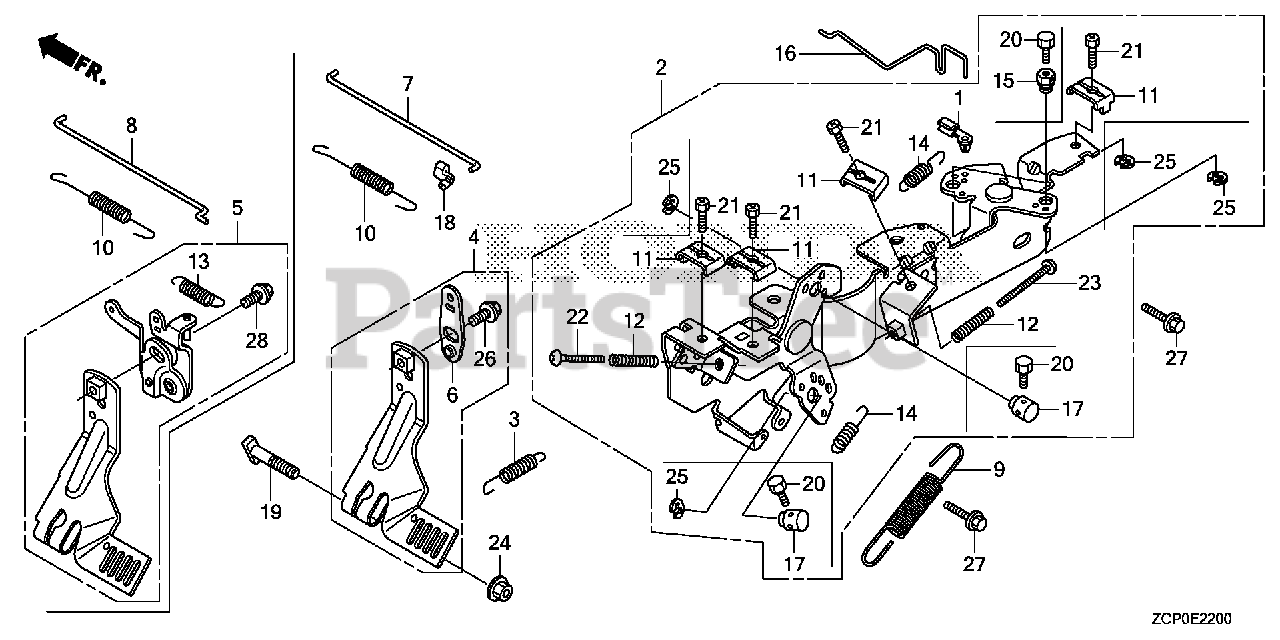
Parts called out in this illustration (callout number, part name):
1	JOINT, ROD
2	CONTROL ASSY.
3	SPRING, STARTER
5	ARM, GOVERNOR
8	ROD, GOVERNOR
9	SPRING, GOVERNOR
10	SPRING, THROTTLE RETURN
11	HOLDER, CABLE
12	SPRING, CONTROL ADJUSTING Use from Engine SN 2327377.
13	SPRING, RETURN
14	SPRING, CABLE RETURN
15	HOLDER, WIRE
16	ROD, CHOKE CONTROL
19	BOLT, GOVERNOR ARM
20	BOLT, RECESSED (4X6)
21	BOLT, RECESSED (5X16)
22	SCREW, PAN (5X40)
24	NUT, FLANGE (6MM)
25	E-RING (5MM)
27	BOLT, FLANGE (6X14)
28	BOLT, FLANGE (6X10)
